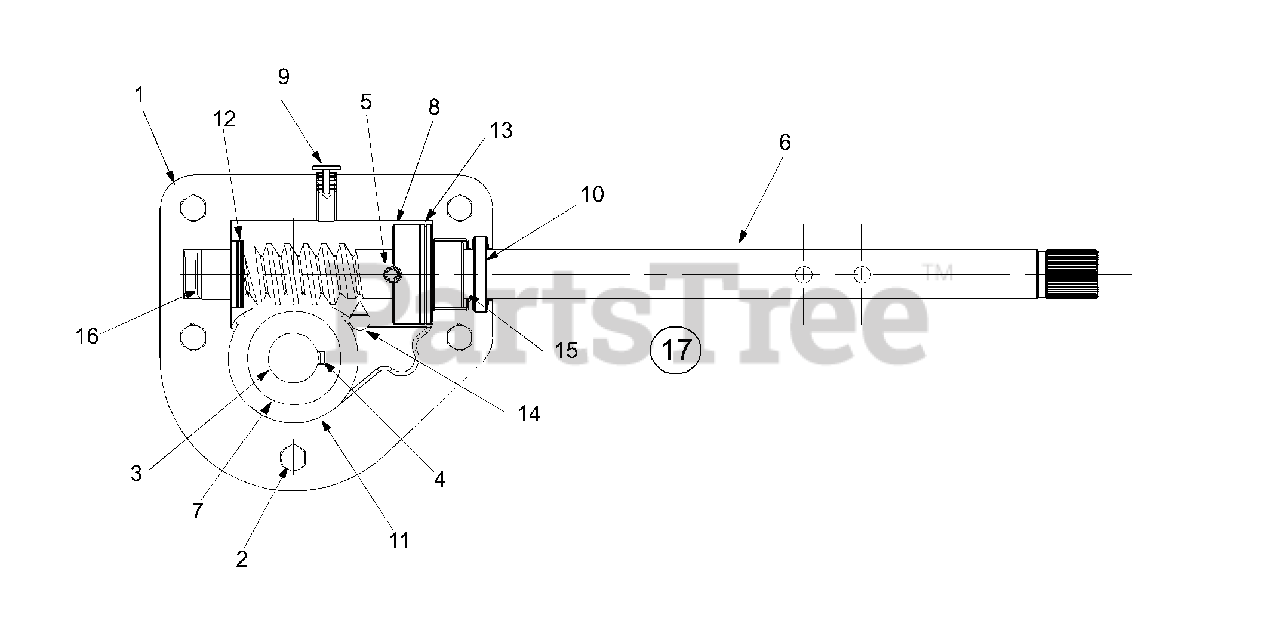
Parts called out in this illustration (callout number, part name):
1	Housing - R.H.
2	Hex Screw 1/4-20 x .75
3	Spiral Axle 22" D
4	Key
5	Pin-Spiral
6	Shaft-Worm
7	Gear-Worm
8	Collar-Thrust
10	Seal-Oil
11	Washer-Flat
12	Washer-Flat
13	Washer-Flat
14	Grease
15	Bearing-Flange
16	Bearing-Flange
17	Ass'y. Complete 22" D
